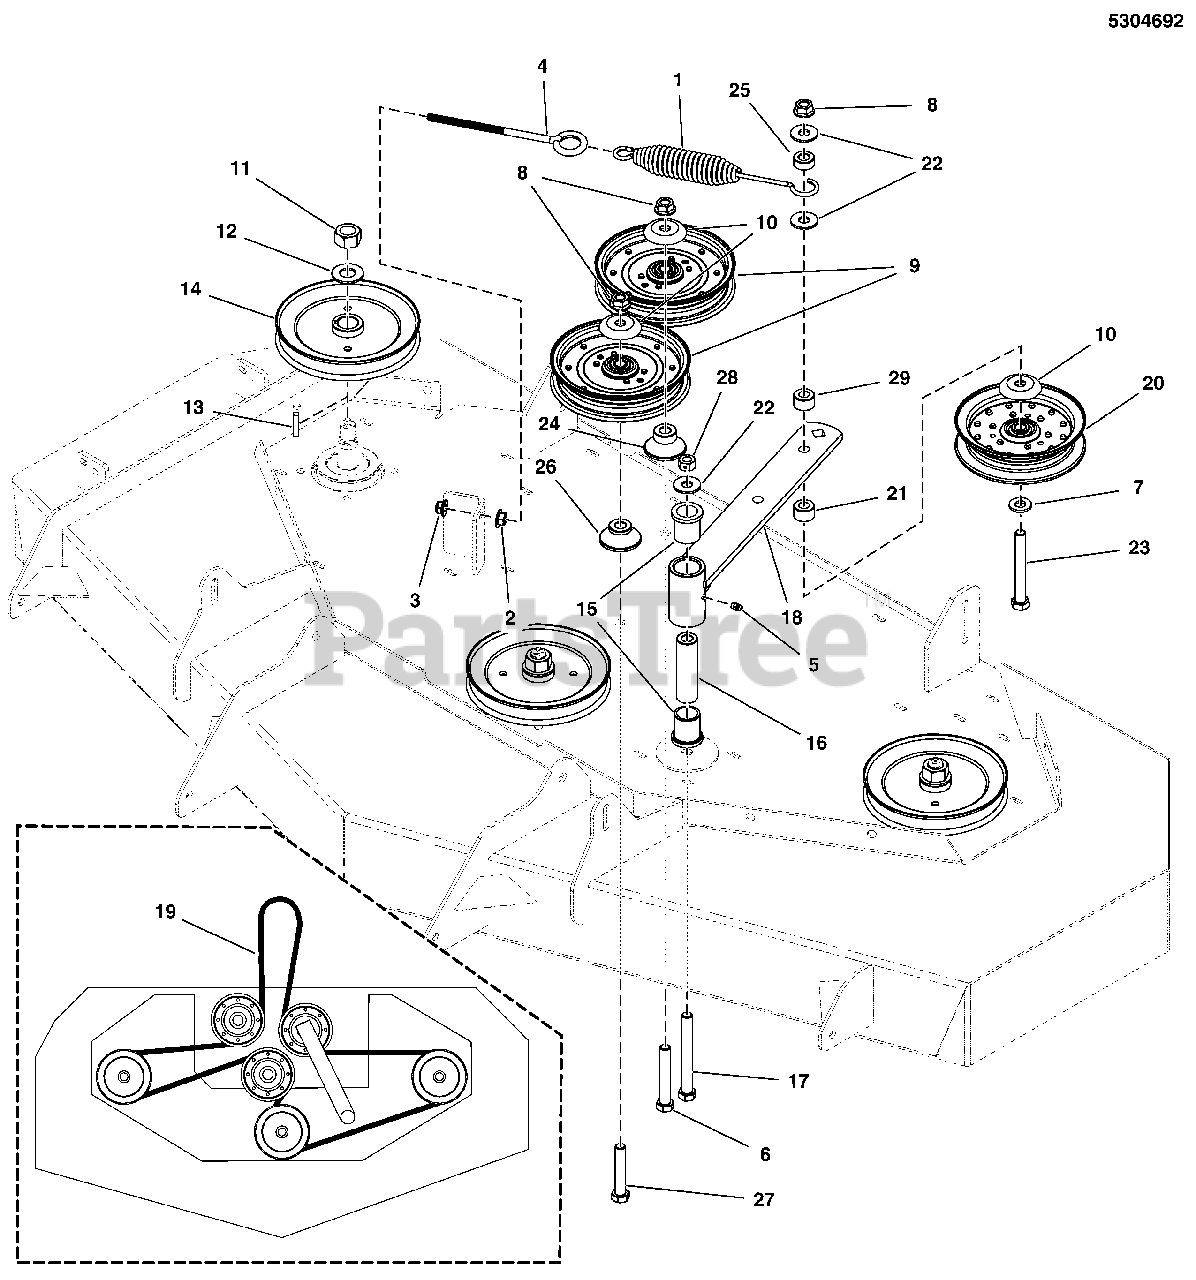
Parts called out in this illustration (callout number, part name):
1	SPRING-EXT, 1.25OD X 9.3LG X .142WR, BLK
2	NUT, 3/8-16 HEX SERRATED FLANGE
3	NUT, Hex Flange, Nylock, 3/8-16
4	EYE BOLT, 3/8-16 X 8, 3THRD, 1EYE, CZ
5	GREASE FITTING, 1/4-28 STRAIGHT
6	BOLT, 1/2-13 X 3-1/4 GD5 CZ
7	WASHER, 1/2 GD9 CZ
8	NUT, 1/2-13 HEX NYLOCK FLANGE
9	PULLEY, FLT IDLR, 6.0 X 1.0 X .50, CZ
10	SHIELD, PULLEY BEARING, CZ
11	NUT, 3/4-16 HEX
12	WASHER, 3/4 BELLEVILLE CL/ZC
13	KEY, 1/4 SQ X 1-1/4
14	PULLEY, Spit, 6.93"
15	BUSHING, FLANGE
16	SPACER, .52 X 1.00 X 3.50
17	BOLT, 1/2-13 X 4-1/2 GD5 CZ
18	WELD, IDLER ARM - 52" - BLK
19	BELT, 5V, 178.25"EL, ARAMID, WRAP RC
21	SPACER, .52 X 1.00 X .63, CZ
22	WASHER, 1/2 USS
23	BOLT, 1/2-13 X 4 GD5 CZ
24	IDLER MOUNT
25	SPACER, .52 X 1.00 X .44, CZ
26	IDLER MOUNT, .88 HIGH
27	BOLT, 1/2-13 X 2-3/4 GD5 CZ
28	NUT, 1/2-13 HEX SIDE LOCK
29	SPACER, .52 X 1.00 X .56
